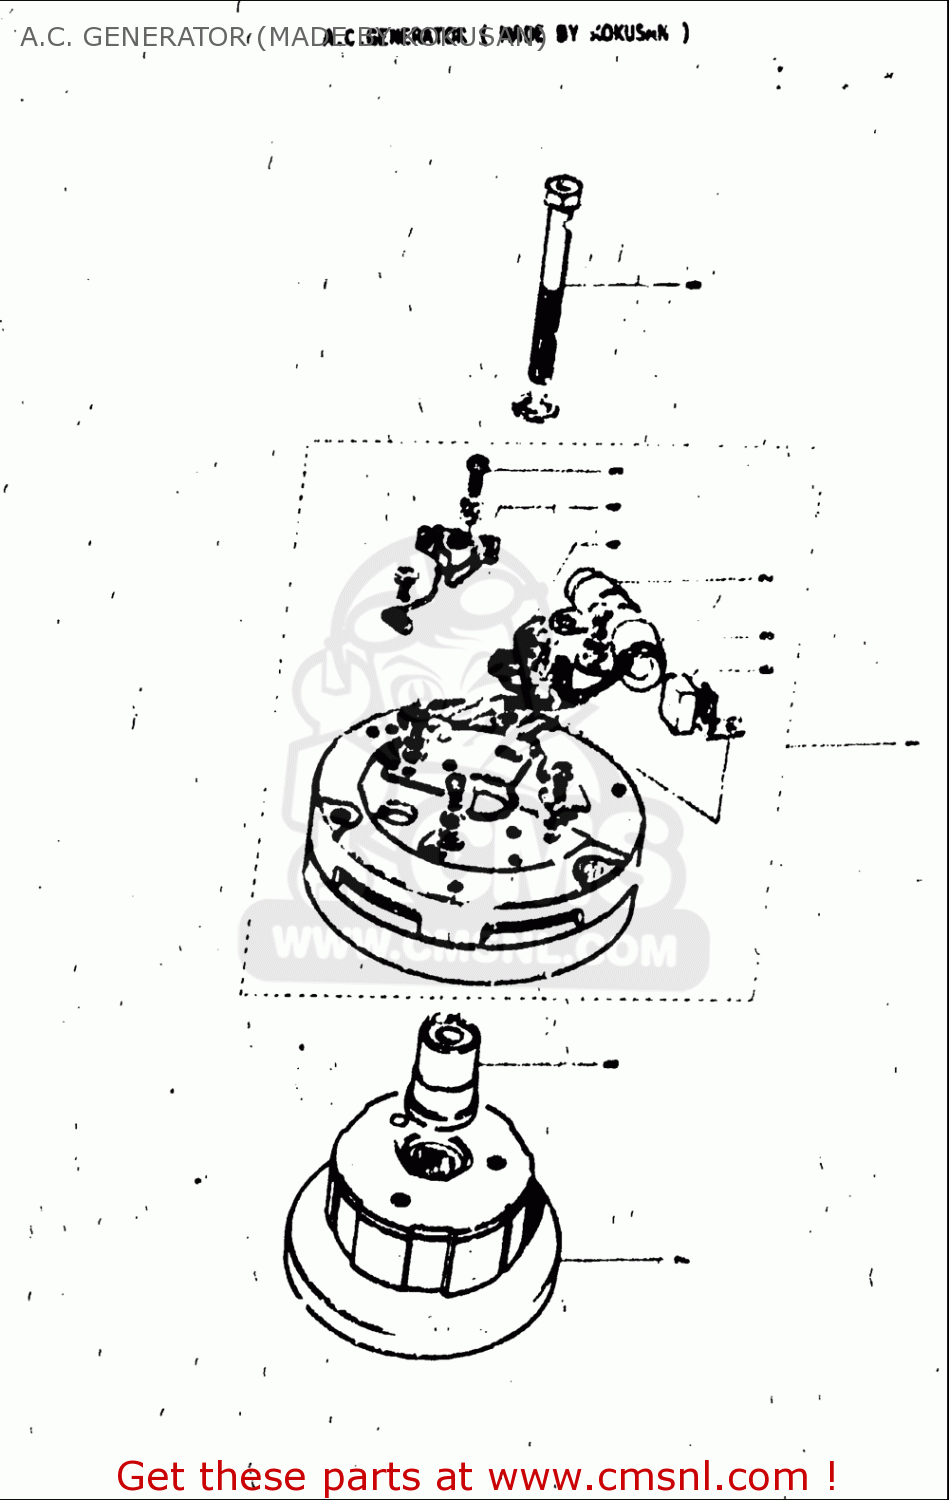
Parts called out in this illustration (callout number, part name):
2	CONDENSER
3	CONDENSER
4	POINT ASSY,CONTACT
5	SCREW(4X10)
